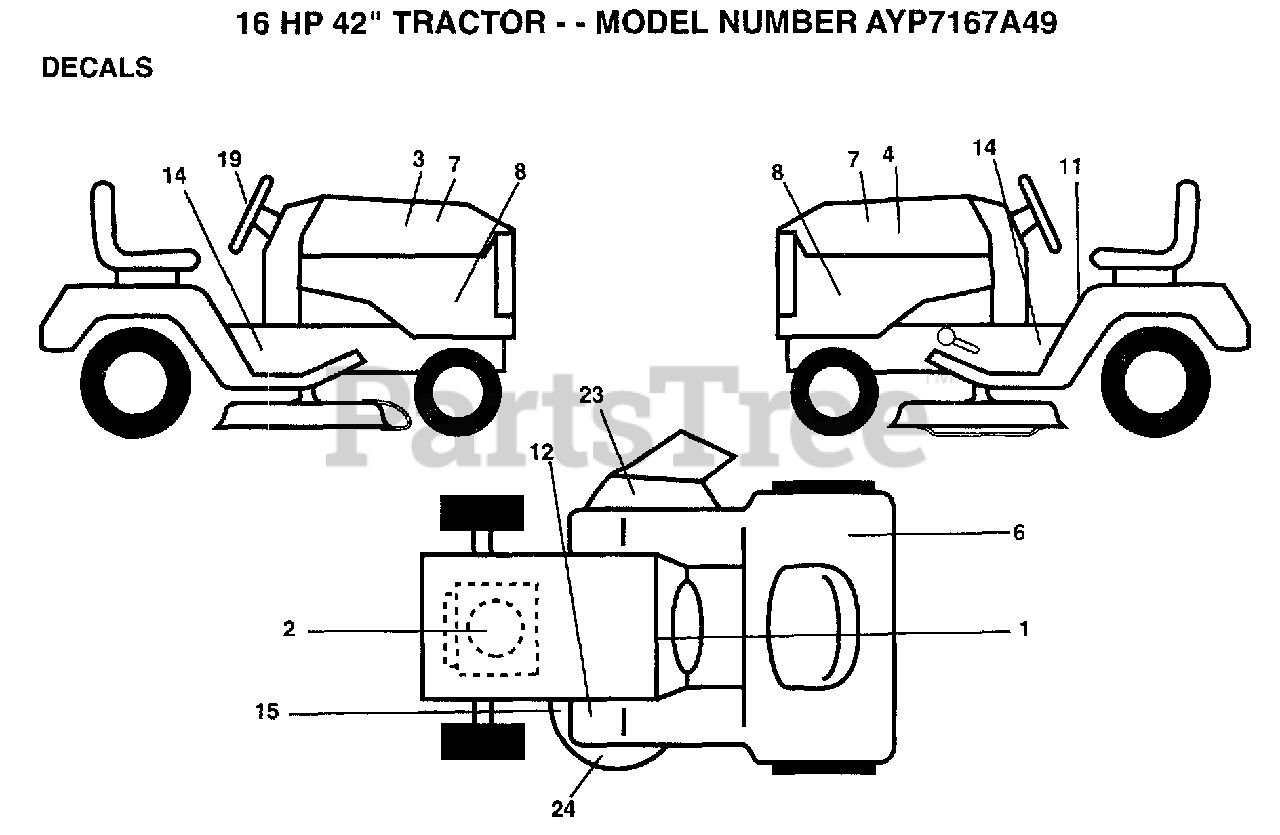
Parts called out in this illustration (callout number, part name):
2	DECAL.ENG.805720
3	DECAL HOOD RH
4	DECAL HOOD LH
7	DECAL PANEL SIDE
11	DECAL
14	DECAL CHASSIS WIZ
15	DECAL
19	DECAL STEER WHL
23	DECAL DECK MULCH
24	DECAL DECK WIZ +
